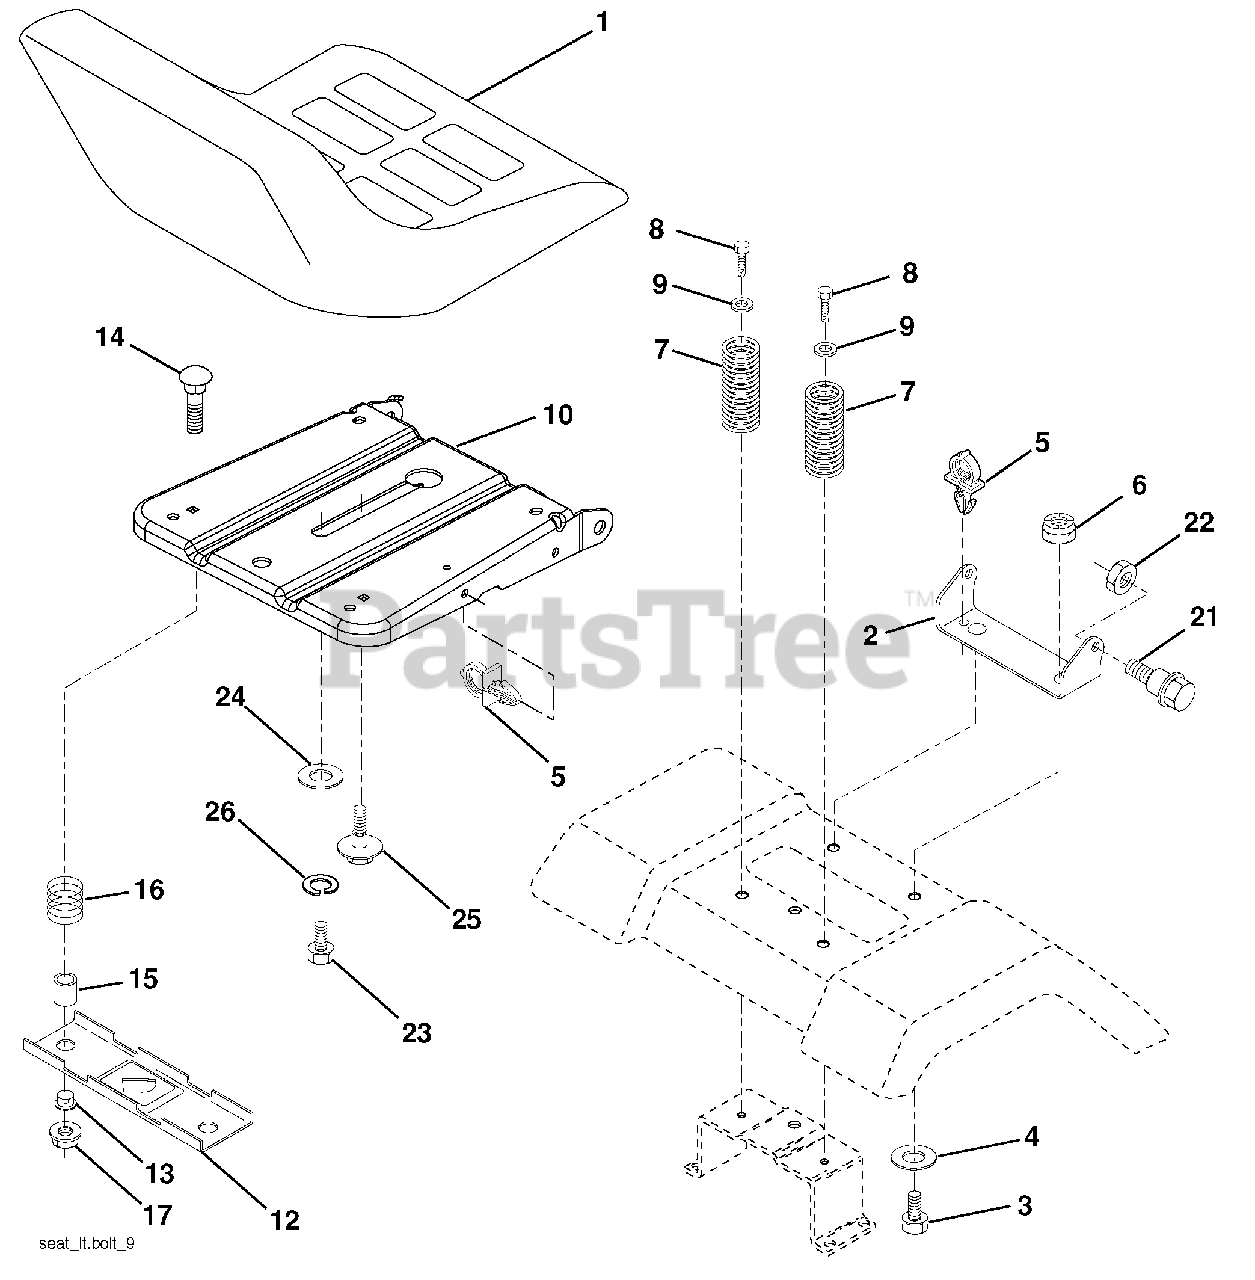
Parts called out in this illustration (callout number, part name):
1	Seat
2	Bracket Seat Pivot
3	Bolt Hex 3/8-16 x 1
4	Washer 13/32 x 1 x10 Ga.
5	Clip Push-In Hinged
6	Nut Lock Hex w/Ins 3/8 - 16
7	Spring Seat Cprsn 2 250 Blk Zi
8	Screw 3/8-16 x 1.5
9	Washer 13/32 x 1 x 14 Ga.
10	Pan Asm. Seat
12	Bracket Pnt Mounting Switch
13	Bushing Snap Blk Nyl
14	Bolt Rdhd Sht Nk 1/4 - 20 x 1 -1/2
15	Spacer Split .28 x .96
16	Spring Cprsn
17	Nut Lock 1/4 Lge Flg
21	Bolt Shoulder 5/16-18 unc-2A
22	Nut Lock Hex w/Ins 5/16 - 18
23	Bolt Hex
24	Washer 17/32 x 1-3/16 x 12 Ga.
25	Bolt Shoulder 5/16-18 x .62
26	Washer Lock Hvy Hlcl Spr 1/2
